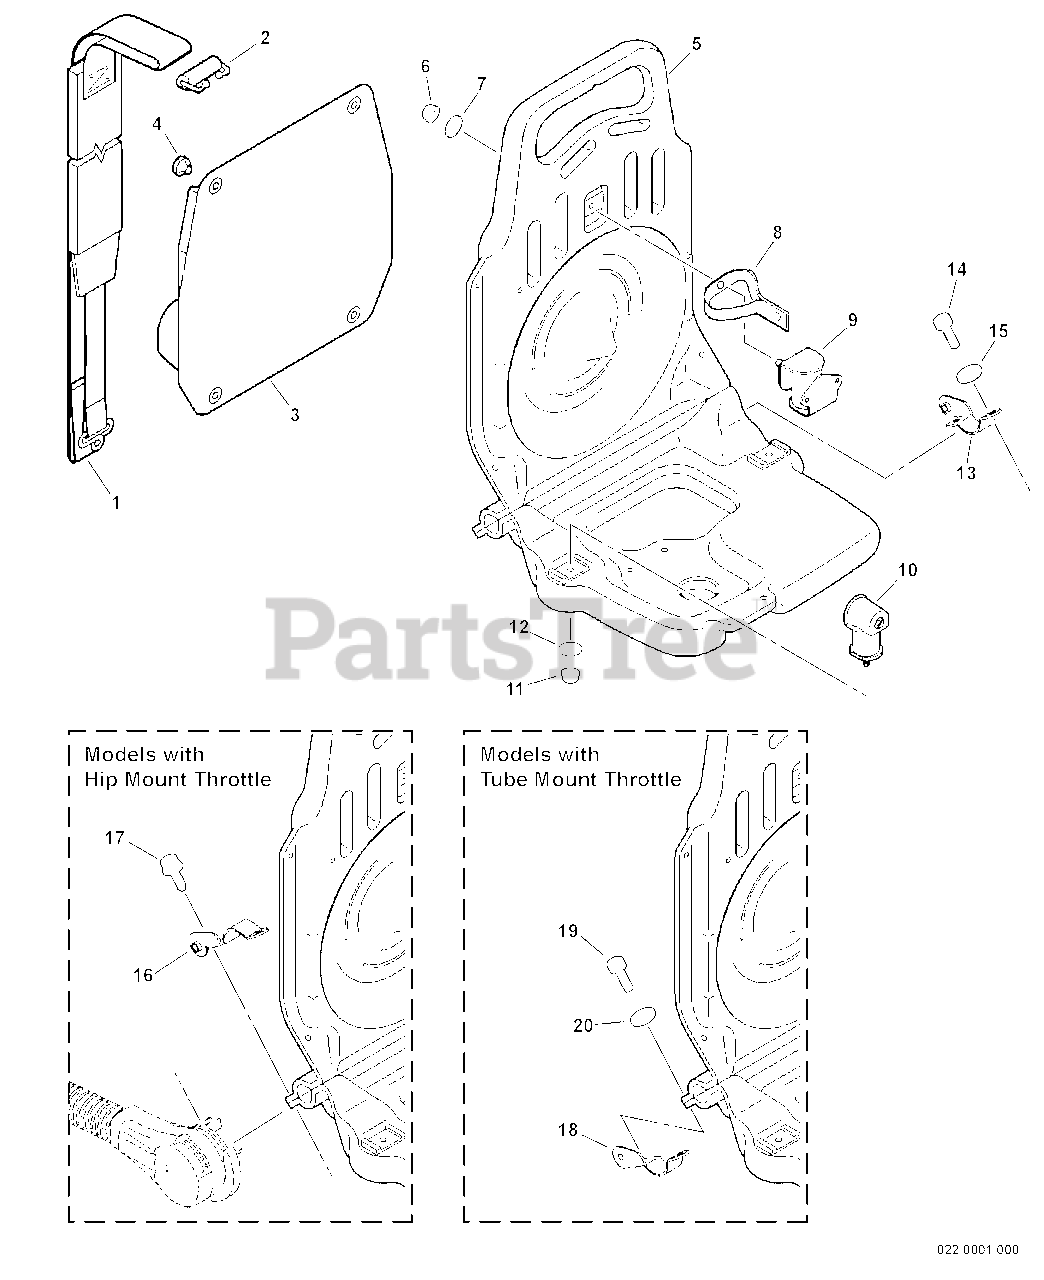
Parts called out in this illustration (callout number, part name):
1	BACKPACK STRAP ASSY
2	RETAINER, HARNESS
3	CUSHION, BACKPACK
5	FRAME, BACKPACK
6	NUT - 5 -- FLANGE
7	WASHER - 5
8	RETAINER
10	CUSHION
11	NUT - 5 -- FLANGE
12	WASHER - 5
13	CONNECTOR, STRAP - RIGHT
14	SCREW - 5X20
15	WASHER - 5
16	CONNECTOR, STRAP - LEFT
17	SCREW - 5X25 -- TAPPING
18	CONNECTOR, STRAP - LEFT
19	SCREW - 5X20
20	WASHER - 5
